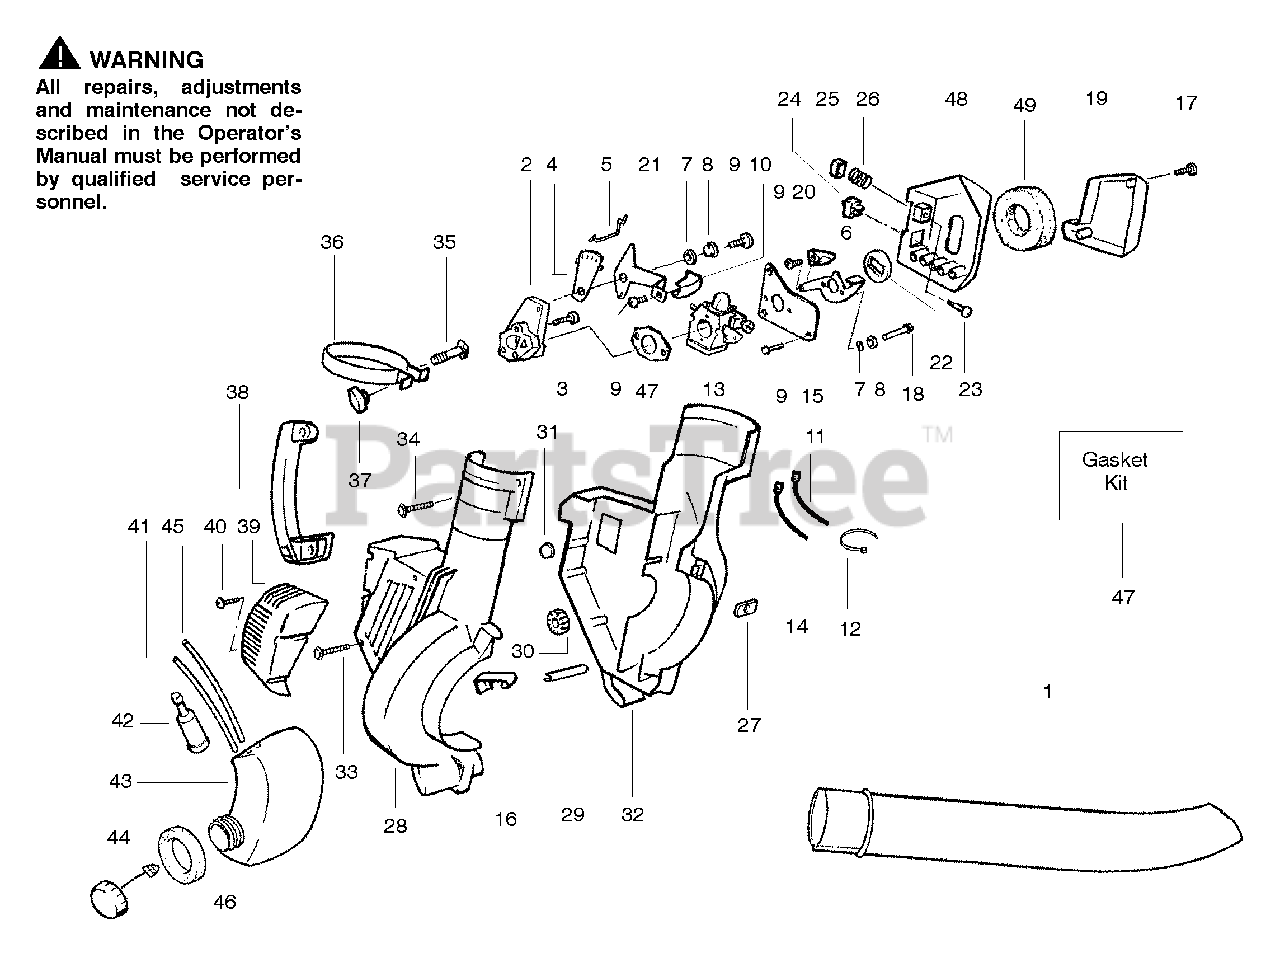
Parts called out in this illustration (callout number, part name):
1	Blower Tube Model 1850
1	Blower Tube Model 2000
2	Carburetor Adaptor
4	Throttle Plate
5	Throttle Linkage
6	Choke Lever
8	Choke Spacer
10	Knob-Throttle Lever
11	Leadwire-Switch
12	Wire Clamp
13	Carburetor Ass'y. (WA-229)
14	Leadwire-Ground
15	Choke Plate
16	Spring Cover Latch
19	Air Box Cover
20	Knob-Choke Lever
21	Throttle Lever
22	Filter-Choke Plate
23	Retainer-Purge Button
25	Purge Button
26	Spring-Purge Button
28	Housing-Right
29	Guide Starter Rope
30	Isolator
31	Isolator
32	Housing-Left
36	Clamp-Blower Tube
39	Muffler Cover
41	Line Kit-Carb/Purge
42	Fuel Pick-up Ass'y.
43	Fuel Tank Ass'y.
44	Gasket-Fuel Tank
45	Line Kit-Tank/Purge
46	Fuel Cap w/Retainer
47	Gasket Kit
49	Air Filter
